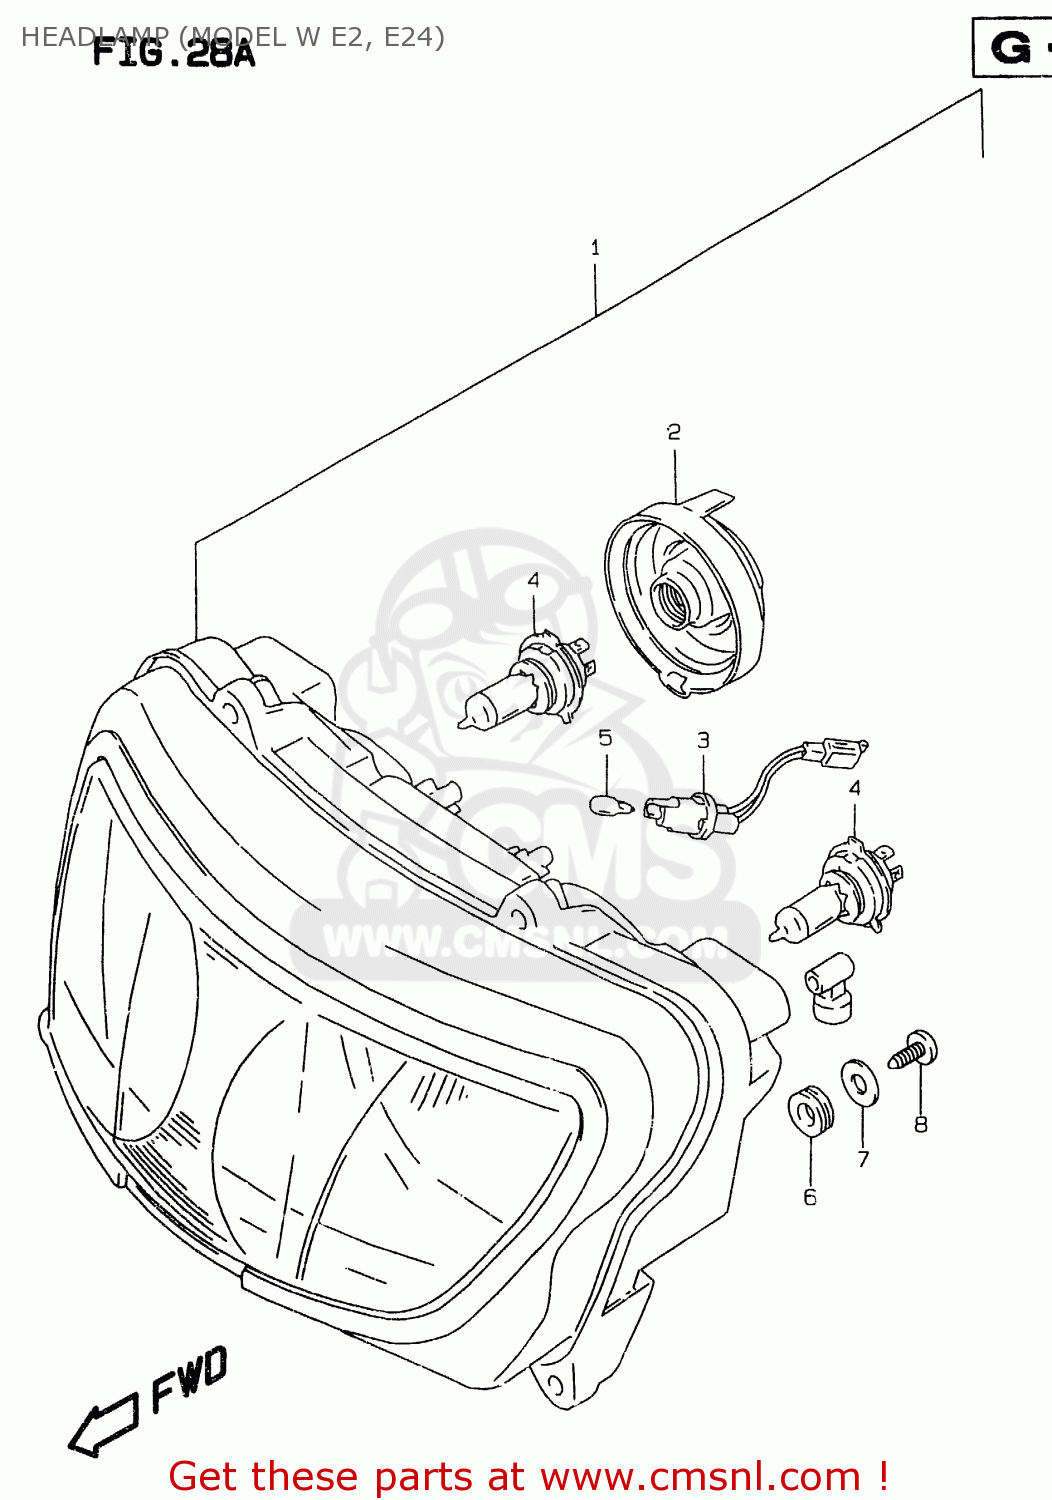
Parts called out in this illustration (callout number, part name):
1	HEADLAMP (E2)
2	COVER,SOCKET
3	SOCKET ASSY
4	BULB(12V60/55W,H4)
5	BULB(12V5W)
6	CUSHION,HEADLAMP
7	WASHER(5.5X18X1)
8	SCREW,SIDE HOL
